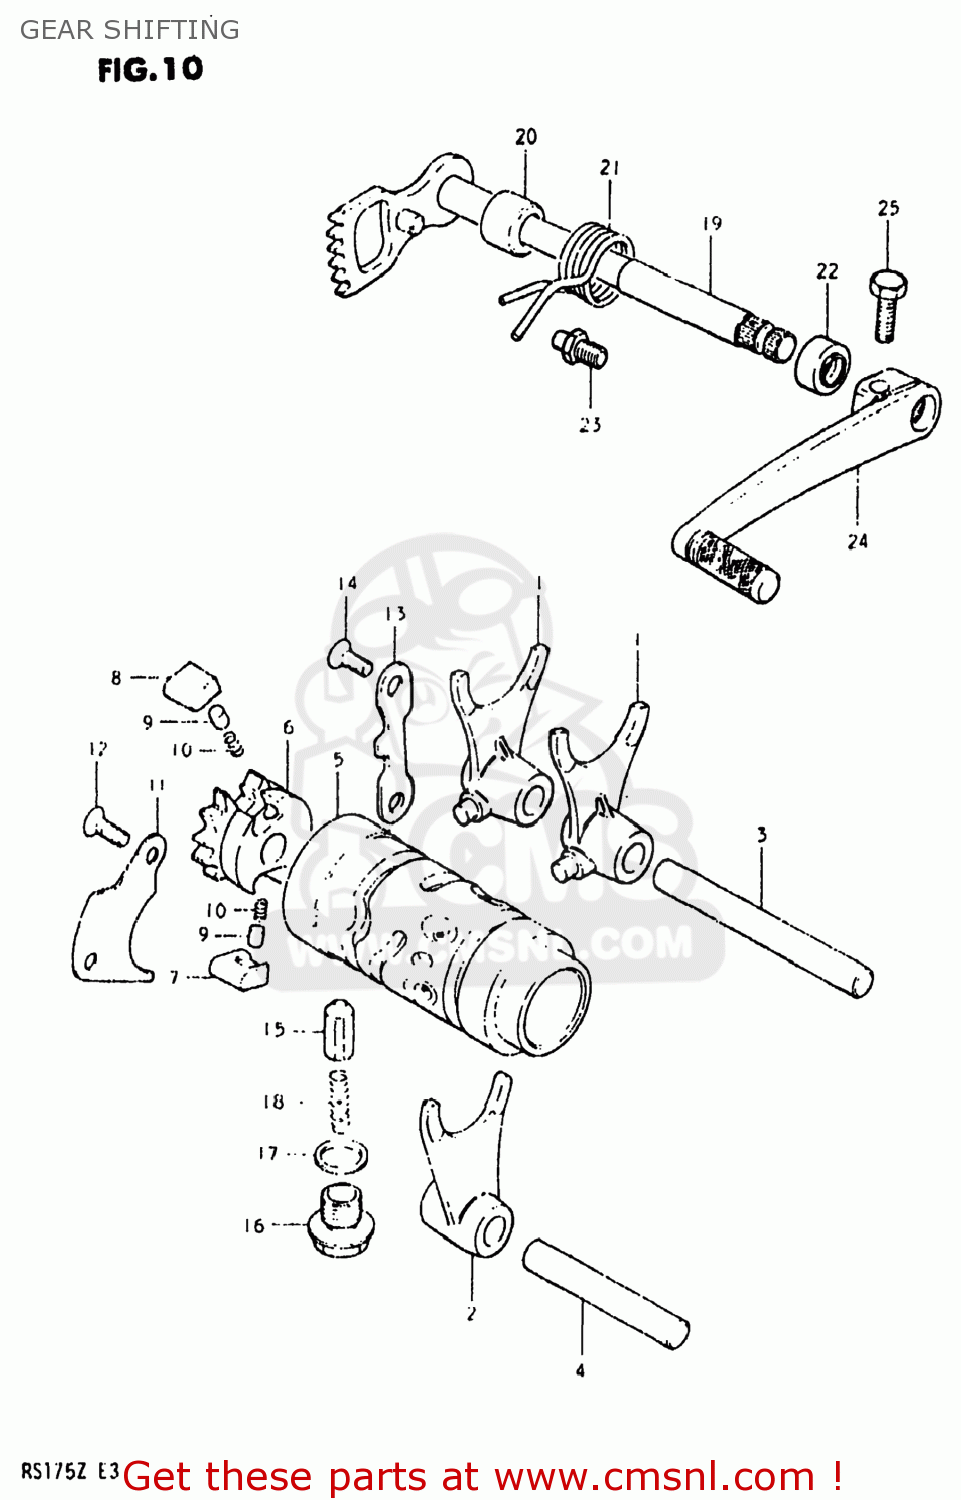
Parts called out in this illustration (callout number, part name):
1	FORK,GEAR SHIFT NO.1
2	FORK,GEAR SHIFT NO.2
3	SHAFT,GEAR SHIFT FORK
4	SHAFT,GEAR SHIFT FORK
5	CAM,GEAR SHIFT
6	RETAINER,GEAR SHIFT CAM
7	PAWL,GEAR SHIFT NO.1
8	PAWL,GEAR SHIFT NO.2
9	PIN(5X8)
10	SPRING
11	LIFTER,GEAR SHIFT PAWL
12	SCREW
13	GUIDE,GEAR SHIFT CAM
14	SCREW
15	STOPPER,GEAR SHIFTING
16	BOLT,GEAR SHAFT CAM STOPPER
17	GASKET(14X19.2X2) (NAS)
18	SPRING
19	SHAFT,GEAR SHIFT
20	SPACER(12X20X15.3)
21	SPRING
22	OIL SEAL
23	STOPPER,GEAR SHIFT CAM
24	LEVER ASSEMBLY,GEAR SHIFTING
25	BOLT
